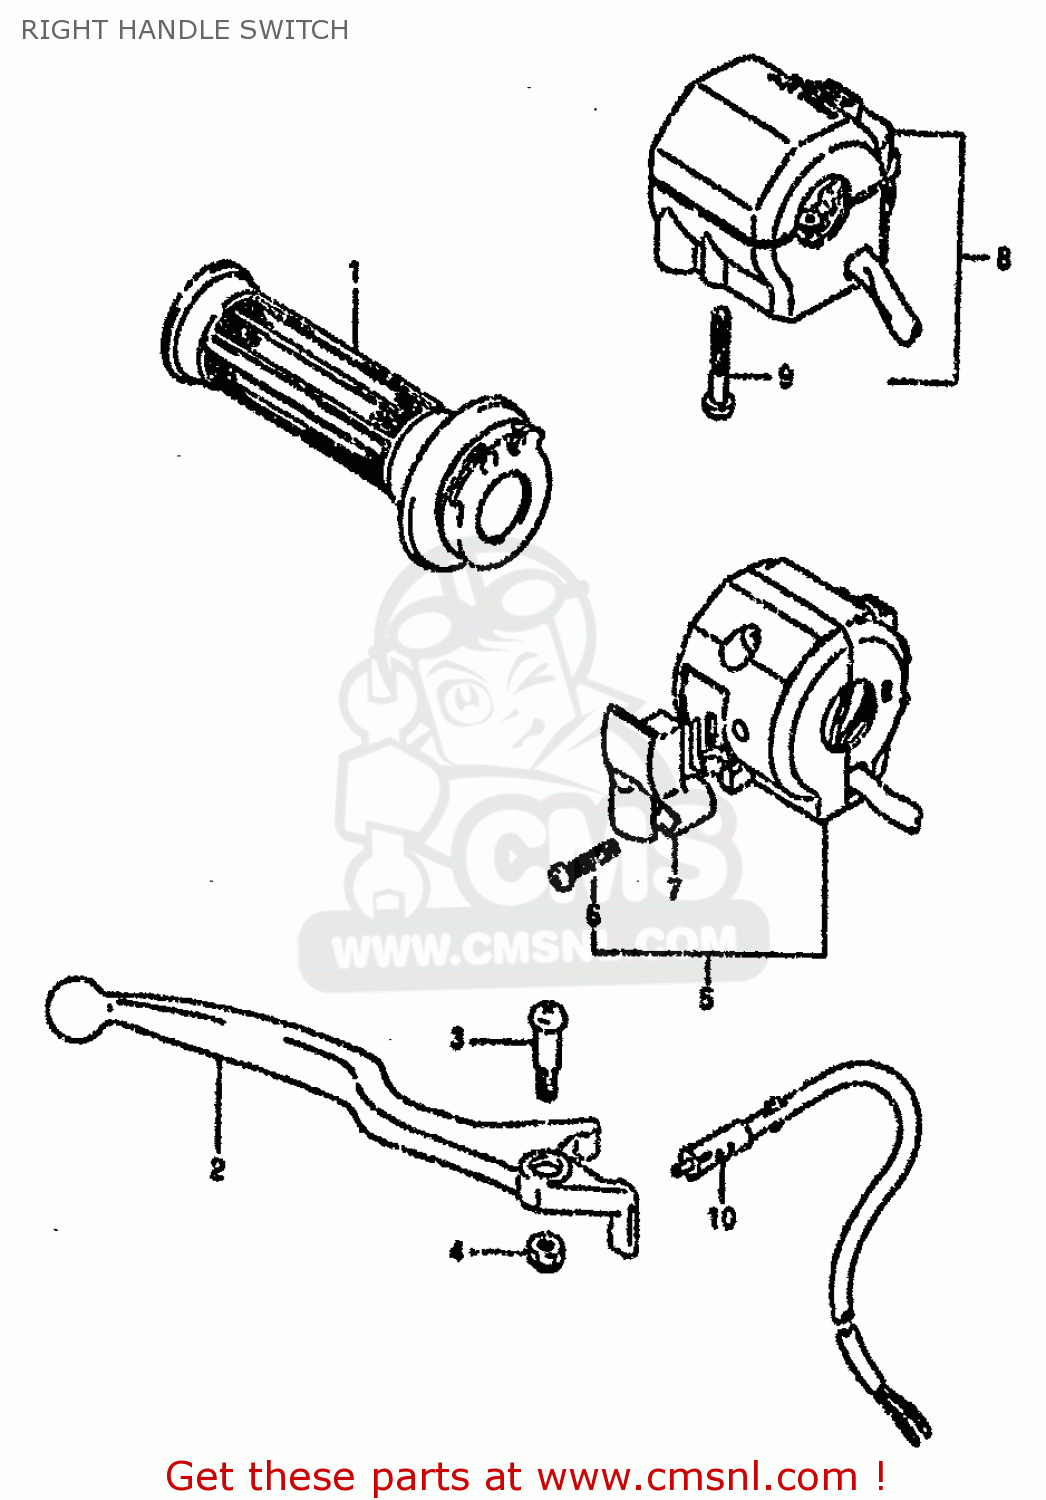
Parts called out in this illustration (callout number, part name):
1	GRIP,THROTTLE
2	LEVER,BRAKE
3	SCREW
4	NUT
5	SWITCH ASSY,HANDLE RH
6	SCREW 5X20
7	COVER
8	SWITCH ASSY, HANDLE RH
9	SCREW, 5X45
10	SWITCH ASSY,STOP
